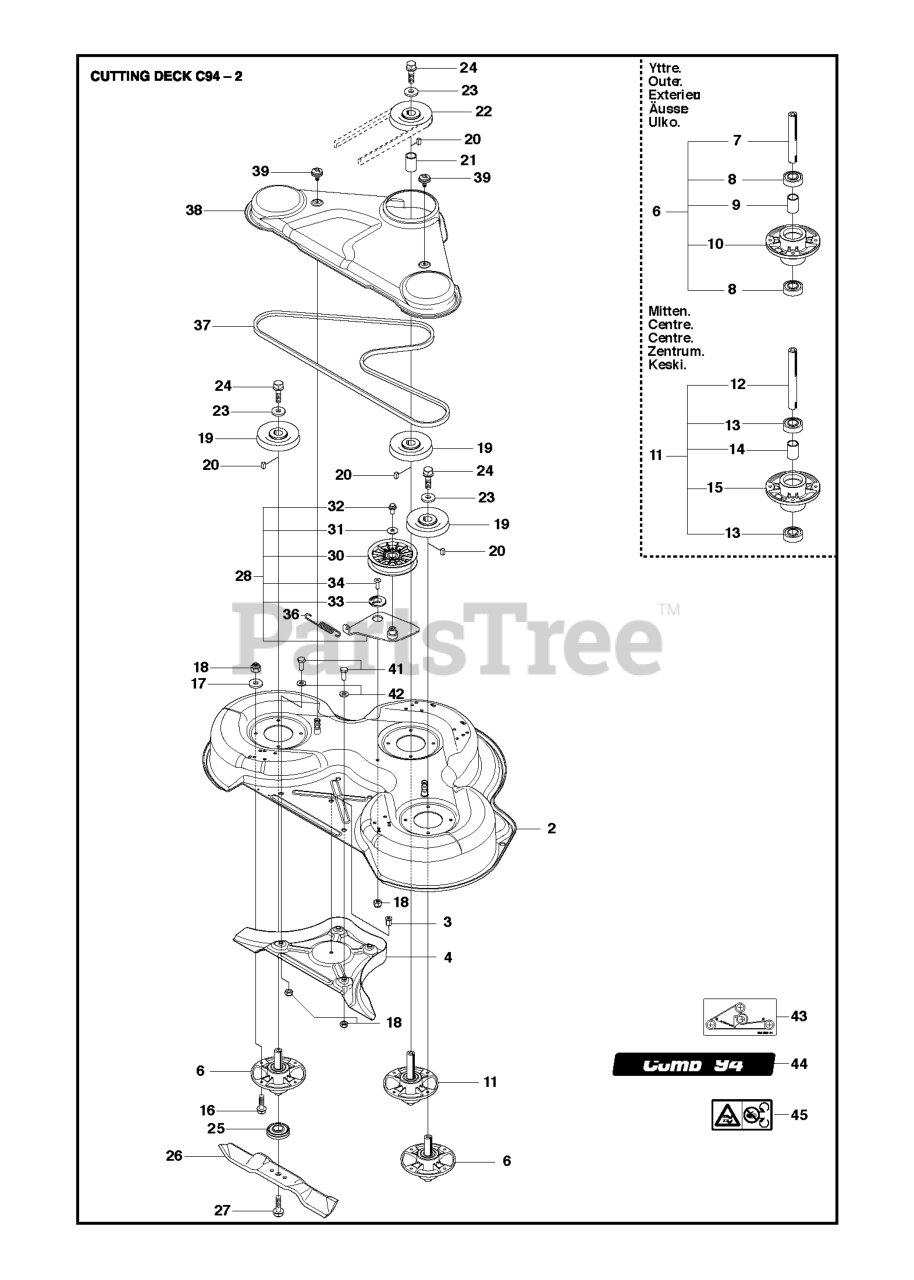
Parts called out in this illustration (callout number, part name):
4	PLUG C93 & C94
6	BLADE HOUSING ASSY
9	SPACING SLEEVE
10	BEARING HOUSING
14	SPACING SLEEVE
15	BEARING HOUSING
17	WASHER BRB 8.4X17
18	LOCKNUT M8
21	SPACING SLEEVE
25	BLADE BRACKET
28	BELT TENSIONER ASSY
33	WASHER SHOULDER ASSY
42	WASHER BRB 8.4X17
